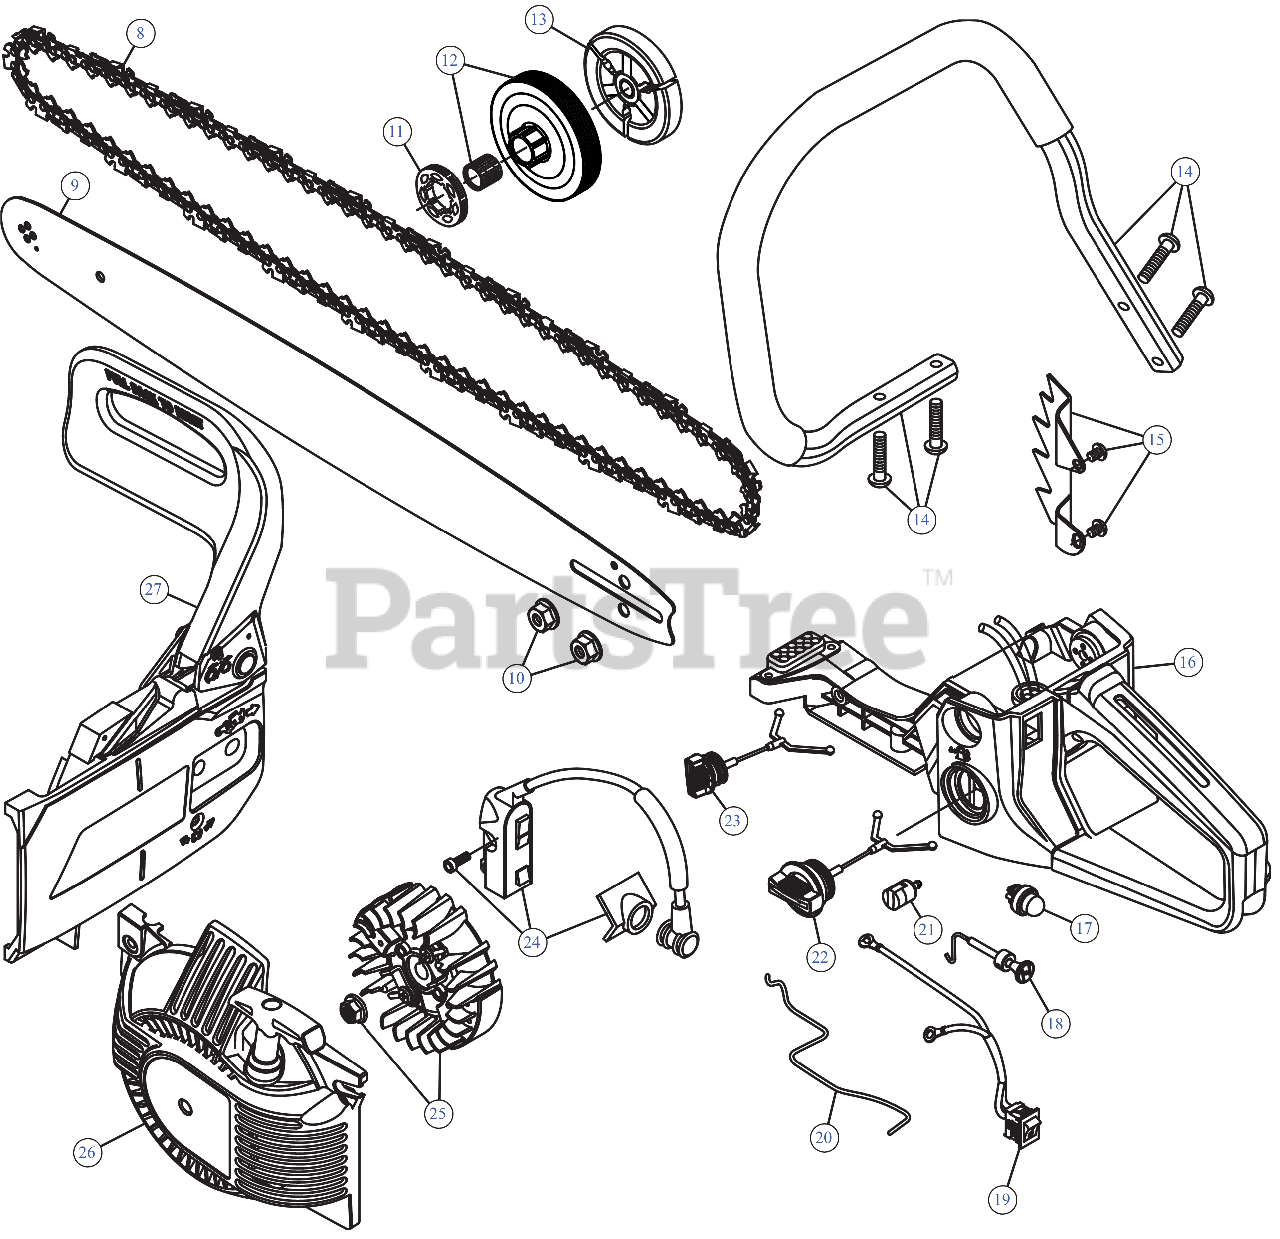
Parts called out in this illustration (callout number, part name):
8	20" CHAINSAW CHAIN
9	CHAINSAW BAR 20" (OREGON)
10	BAR NUT M8
11	SPROCKET
12	CLUTCH DRUM ASSEMBLY
13	CLUTCH ASSEMBLY
14	HANDLE ASSEMBLY
15	SPIKE PLATE W/HDW
16	FUEL HOUSING ASSEMBLY
17	PRIMER BULB YD2500-18410
18	CHOKE LEVER ASSEMBLY
19	SWITCH ASSEMBLY
20	THROTTLE ROD
21	FUEL FILTER YD4600-18034
22	FUEL CAP ASSEMBLY SRS
23	OIL CAP ASSEMBLY
24	MODULE
25	FLYWHEEL
26	RECOIL ASSEMBLY (SBD4620YD4620.8CM-25313)
27	BRAKE ASSEMBLY (SBD4620 YD4620.8CM-27724)
